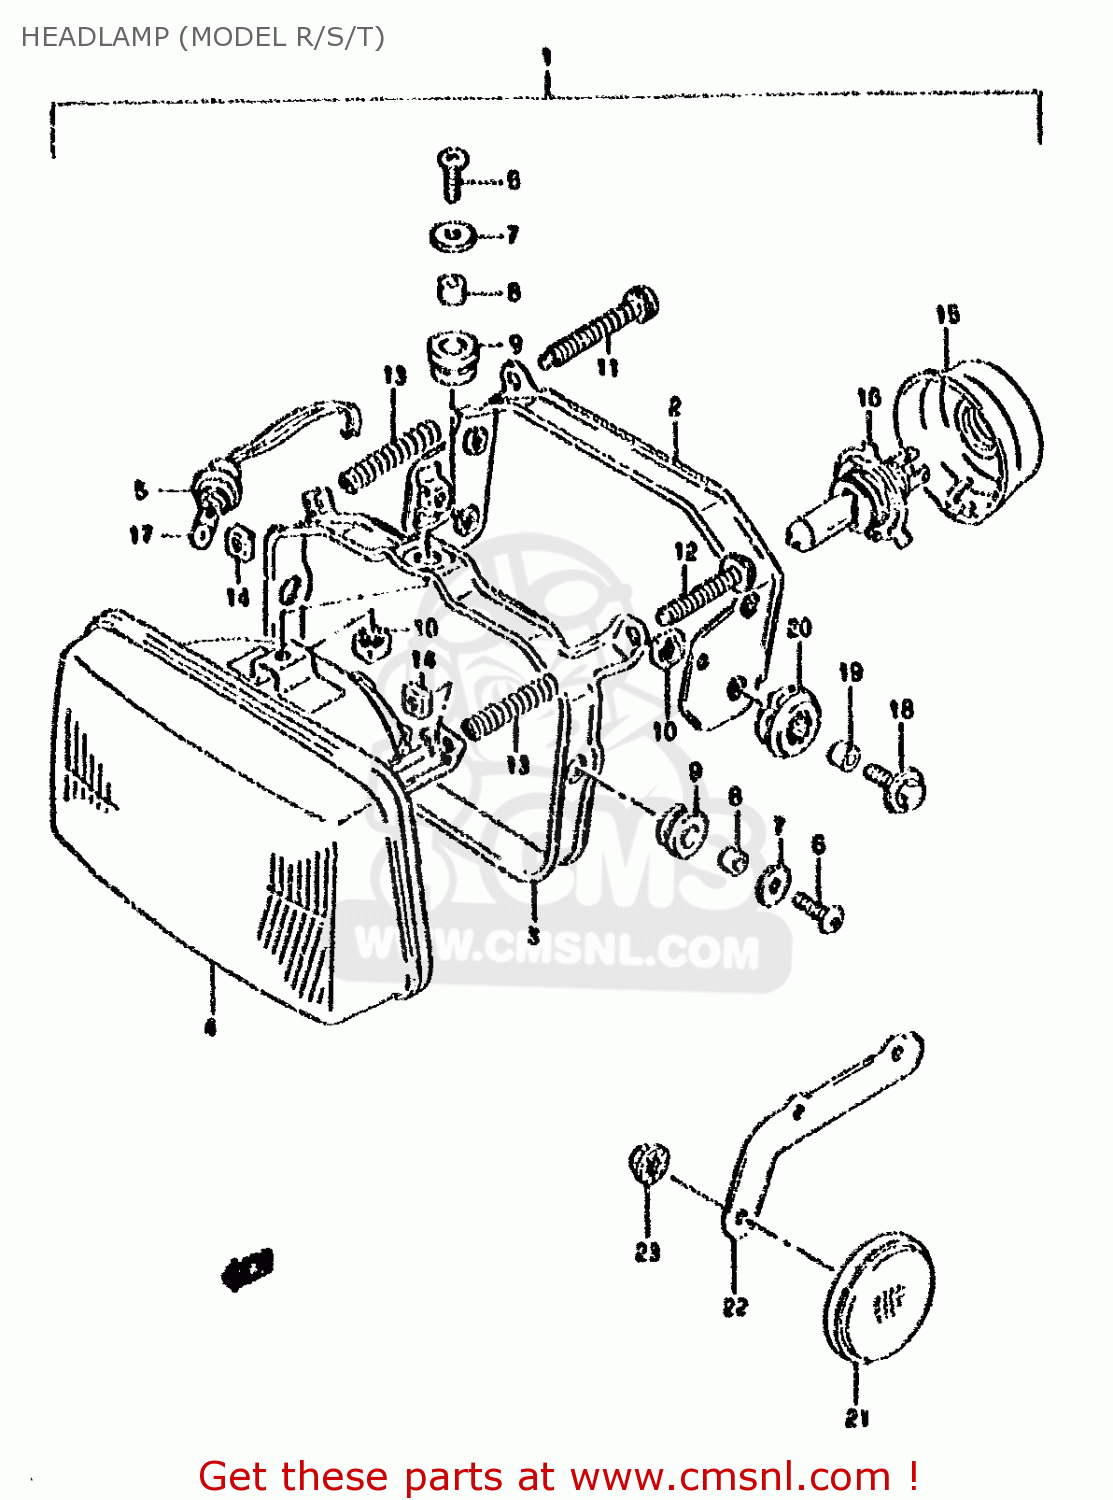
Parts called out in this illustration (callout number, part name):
1	HEADLAMP ASSY
2	HOUSING
3	RING
4	UNIT ASSY
5	SOCKET
6	SCREW
7	WASHER
8	SPACER
9	CUSHION
10	NUT
11	SCREW, 5X45
12	SCREW
13	SPRING,ADJUSTER
14	NUT
15	COVER,SOCKET
16	BULB(12V60/55W,H4)
17	BULB(12V4W)
18	BOLT 6X20
19	SPACER (6.8X10X10)
20	CUSHION
21	REFLECTOR,REFLEX FR
22	BRACKET
23	NUT
